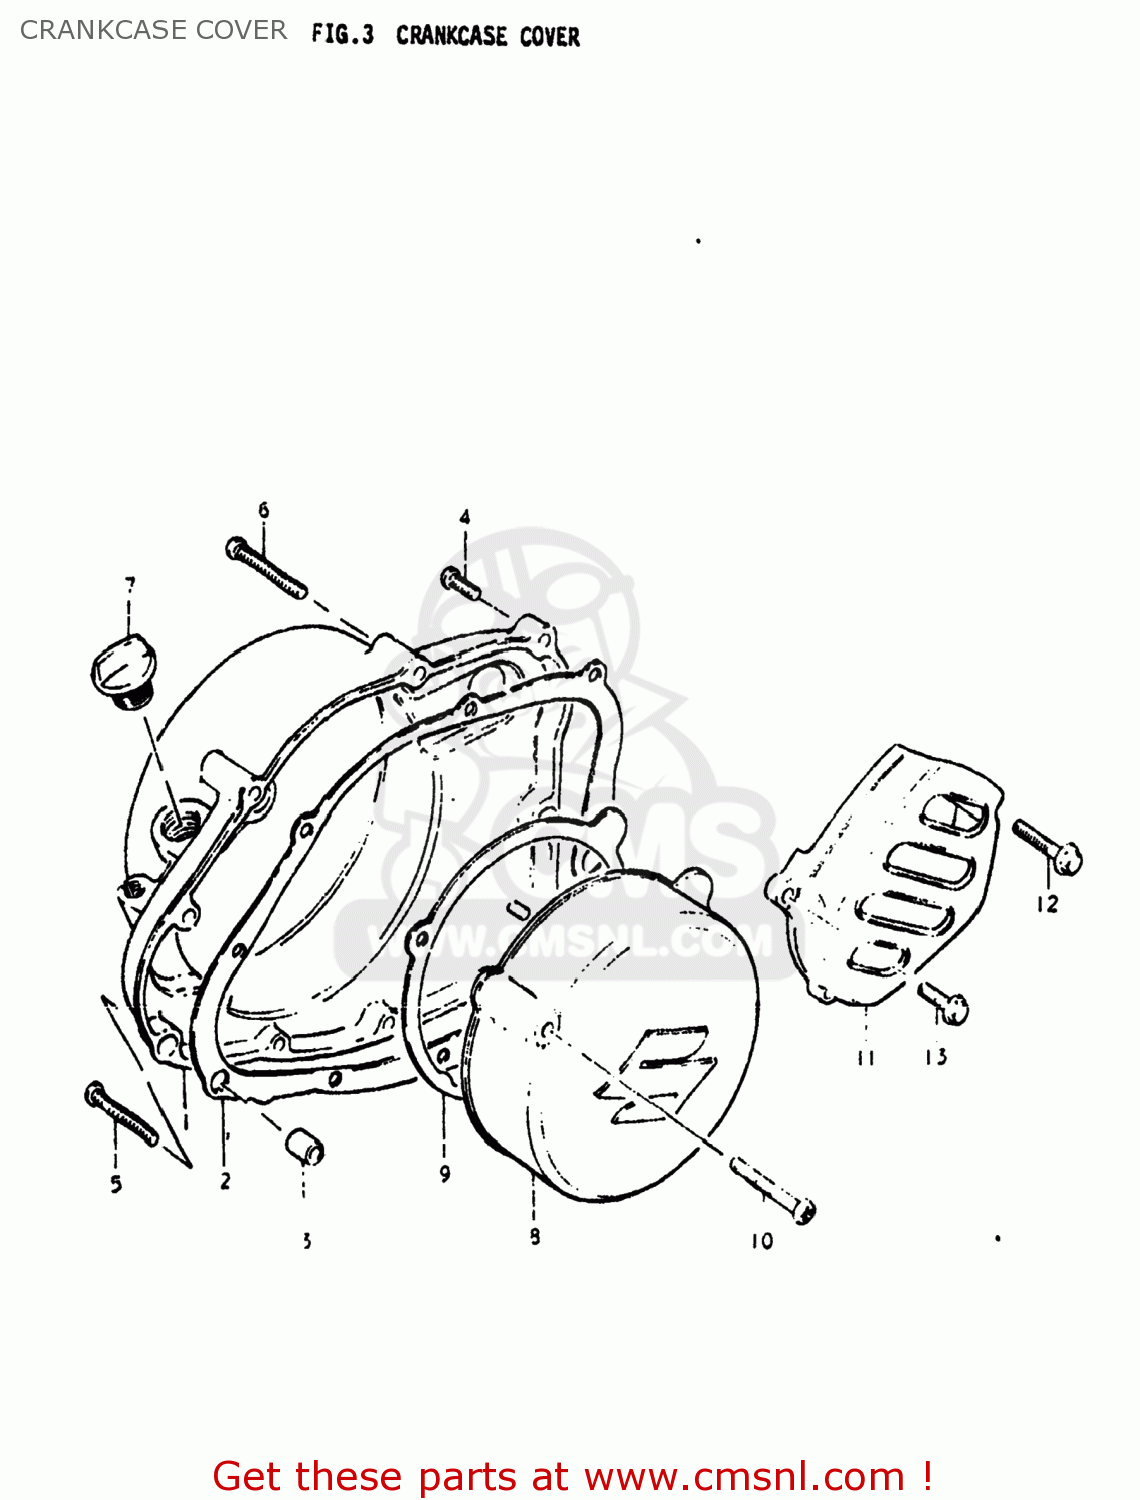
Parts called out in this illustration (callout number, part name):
1	COVER,CLUTCH
2	GASKET,CLUTCH COVER (MCA)
3	PIN
4	SCREW
5	SCREW
6	SCREW (6X45)
7	PLUG,OIL FILTER
8	COVER
9	GASKET,MAGNETO COVER (MCA)
10	SCREW
11	COVER,ENGINE SPROCKET
12	BOLT,UNDER
13	BOLT
